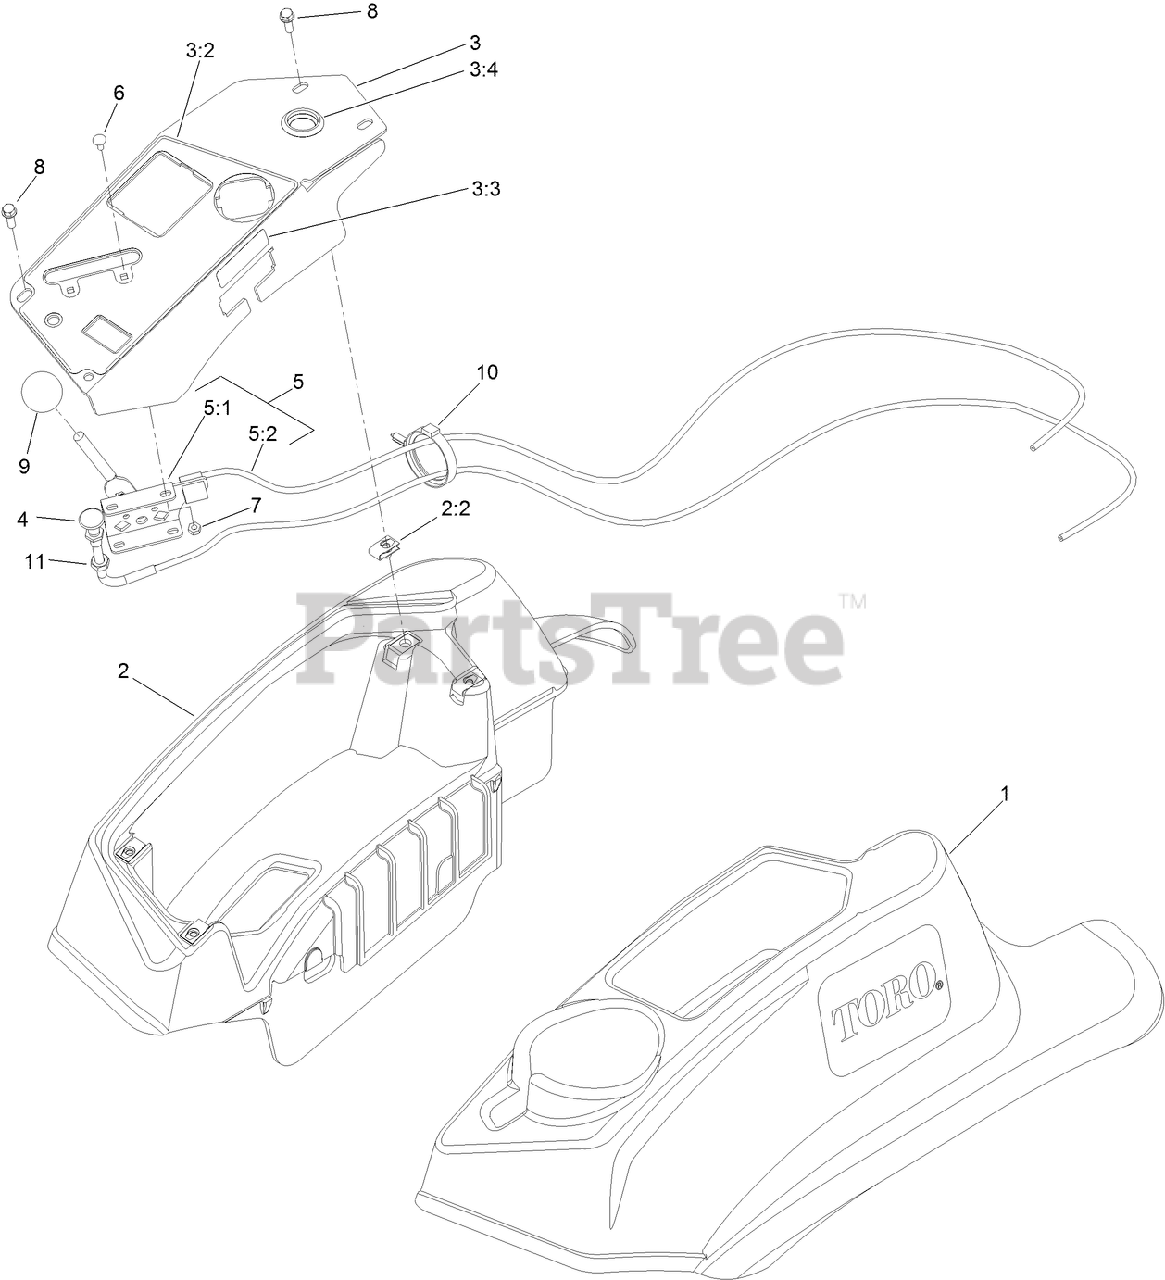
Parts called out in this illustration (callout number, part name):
1	CONSOLE-LH
2	RH CONSOLE ASM
3	CONTROL PANEL ASM
3:2	DECAL-CONTROL PANEL
3:3	DECAL-FUSES
3:4	PLUG-PLASTIC
4	CONTROL-CHOKE
5	THROTTLE CONTROL ASM
5:1	LEVER-THROTTLE
5:2	CABLE-THROTTLE
6	BOLT-CARR
7	NUT-LOCK, NI
8	SCREW-HWH
9	KNOB-BALL
10	CLAMP-HARNESS
11	NUT-HJ
